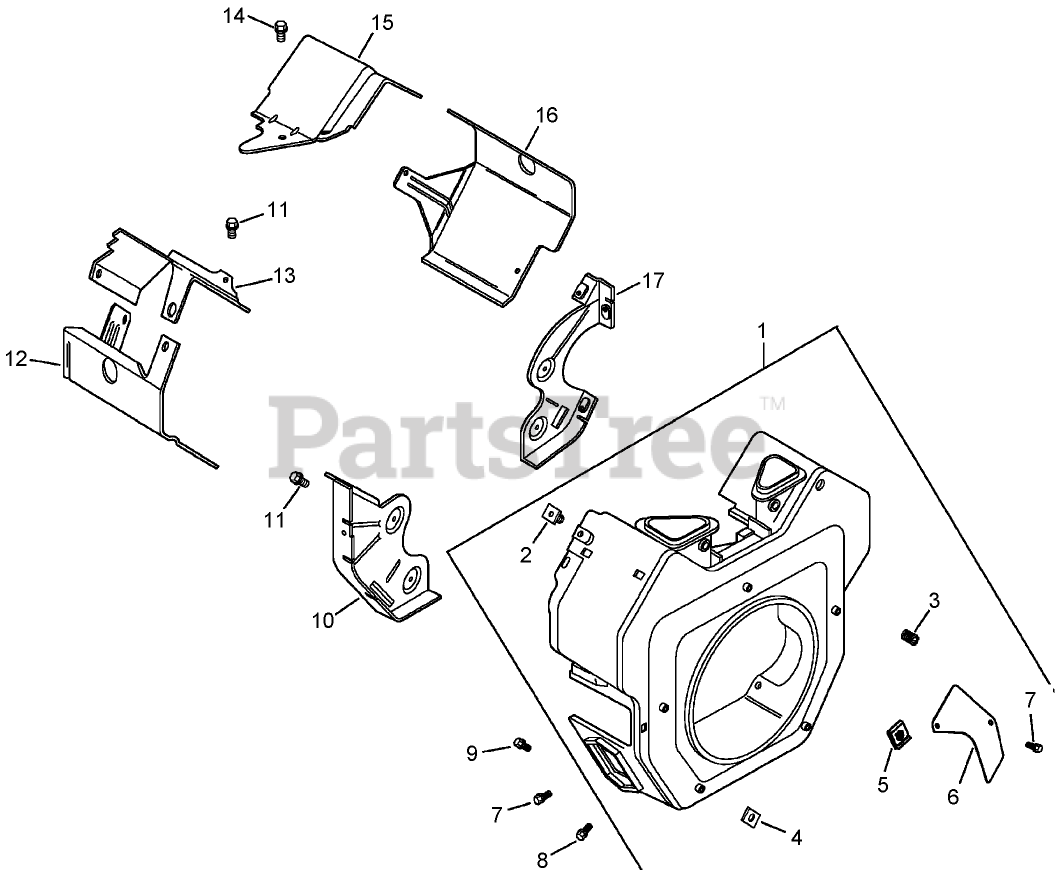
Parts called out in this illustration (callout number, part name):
1	Blower Housing ASM (Includes 2-6, 7 qty. 4])
2	NUT-PLASTIC
3	Screw-Set (10-24X.25)
4	Nut-Plastic
5	Clip-Mounting
6	Cover-Access
7	SCREW-FLANGE, THREAD FORMING (M5X0.8X16)
8	Screw-Hex Flange, Heavy (M5x0.8x16)
9	SCREW-FLANGE, THREAD FORMING (M5X.8X20)
10	Plate-Backing (No. 2 Side)
11	SCREW-FLANGE, THREAD FORMING (M6X1.0X16)
12	Baffle-Barrel, Cylinder (No. 2 Side)
13	Baffle-Valley (No. 2 Side)
14	SCREW-HHFTF (M5X.80X10)
15	BAFFLE-VALLEY (No. 1 SIDE)
16	Baffle-Barrel, Cylinder (No. 1 Side)
17	Plate-Backing (No. 1 Side)
